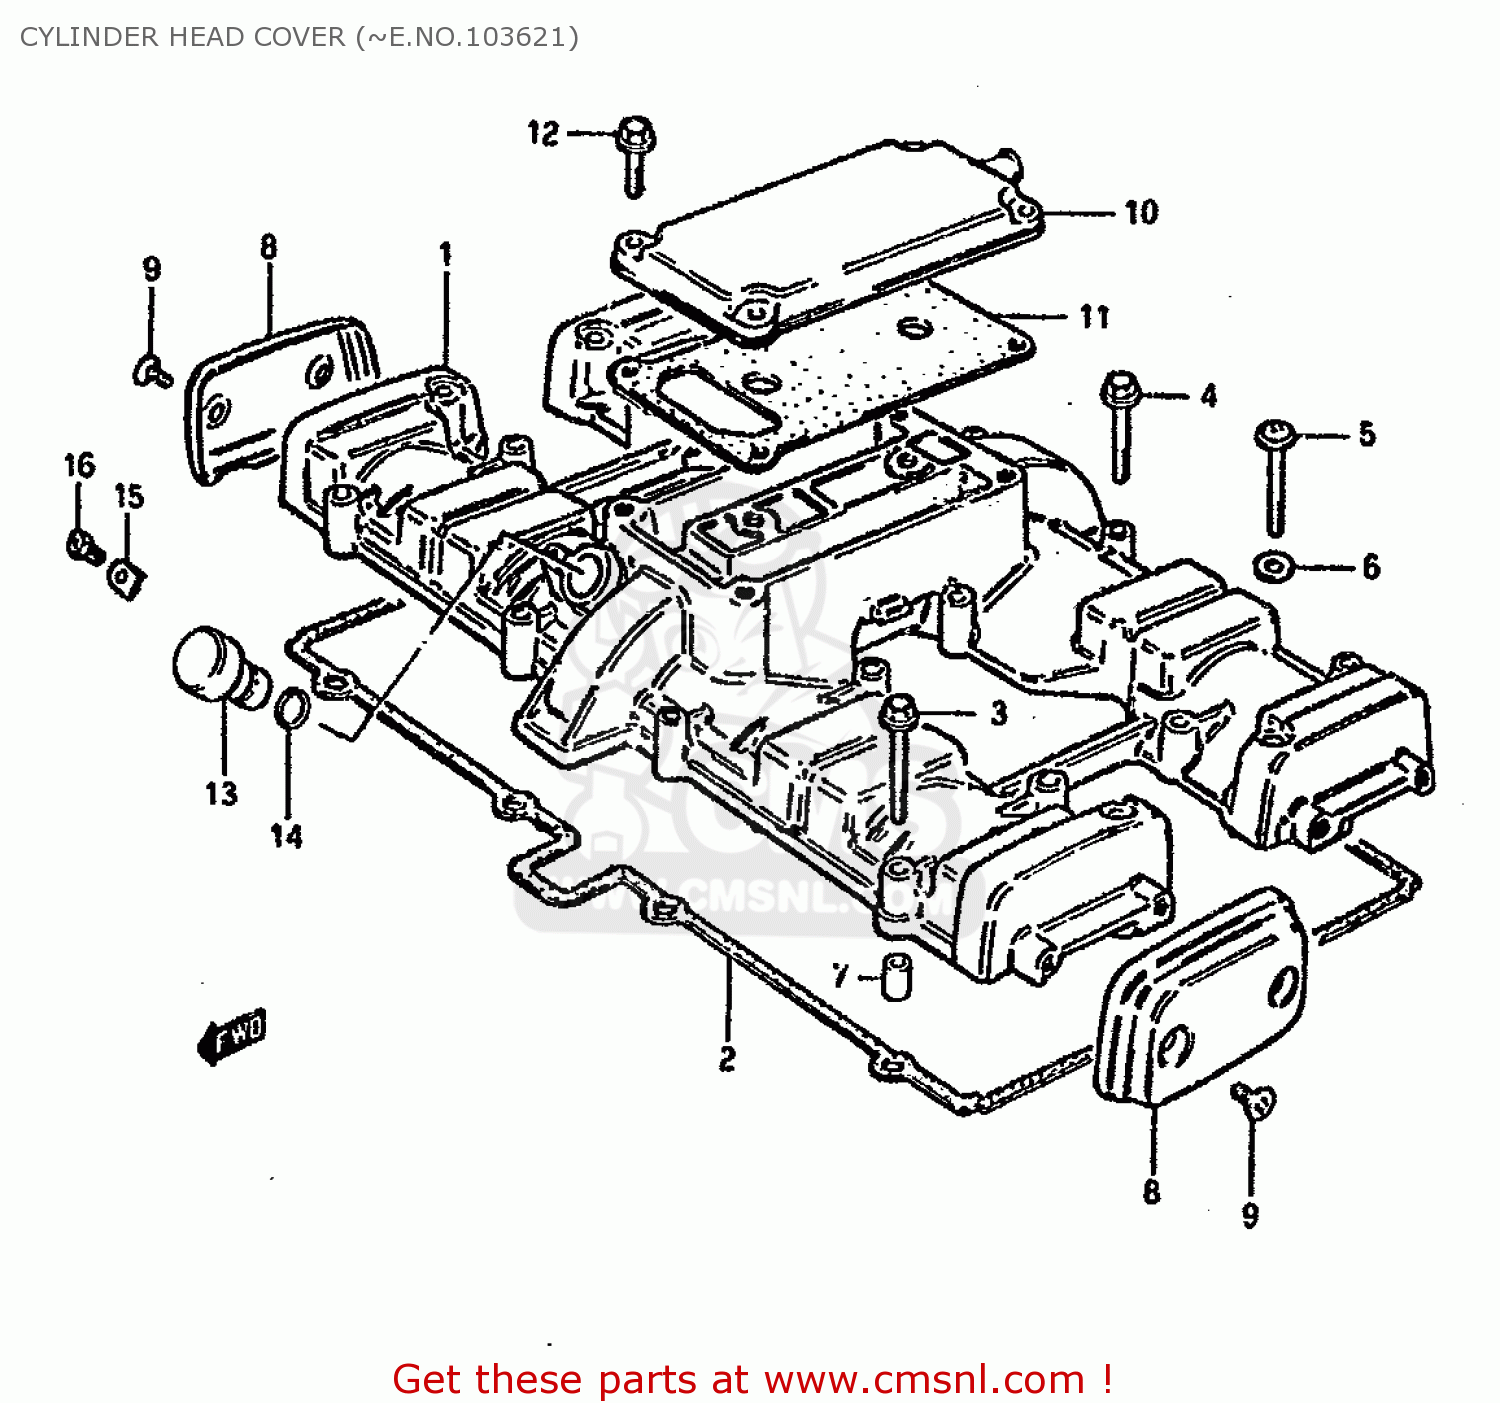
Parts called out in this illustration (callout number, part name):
1	COVER,CYLINDER HEAD
2	GASKET,CYLINDER HEAD COVER (MCA)
3	BOLT
4	BOLT 6X35
5	SCREW 6X40
6	GASKET (NAS)
7	PIN(6.2X8X11)
8	CAP,CYLINDER HEAD COVER
9	SCREW(5X12)
10	COVER,BREATHER
11	GASKET (MCA)
12	BOLT,REAR
13	PLUG,TACH GEAR SLEEVE HOLE
14	SEAL,TACHOMETER DRIVEN
15	PLATE,TACH DRIVE GEAR SLEEVE
16	SCREW(5X12)
